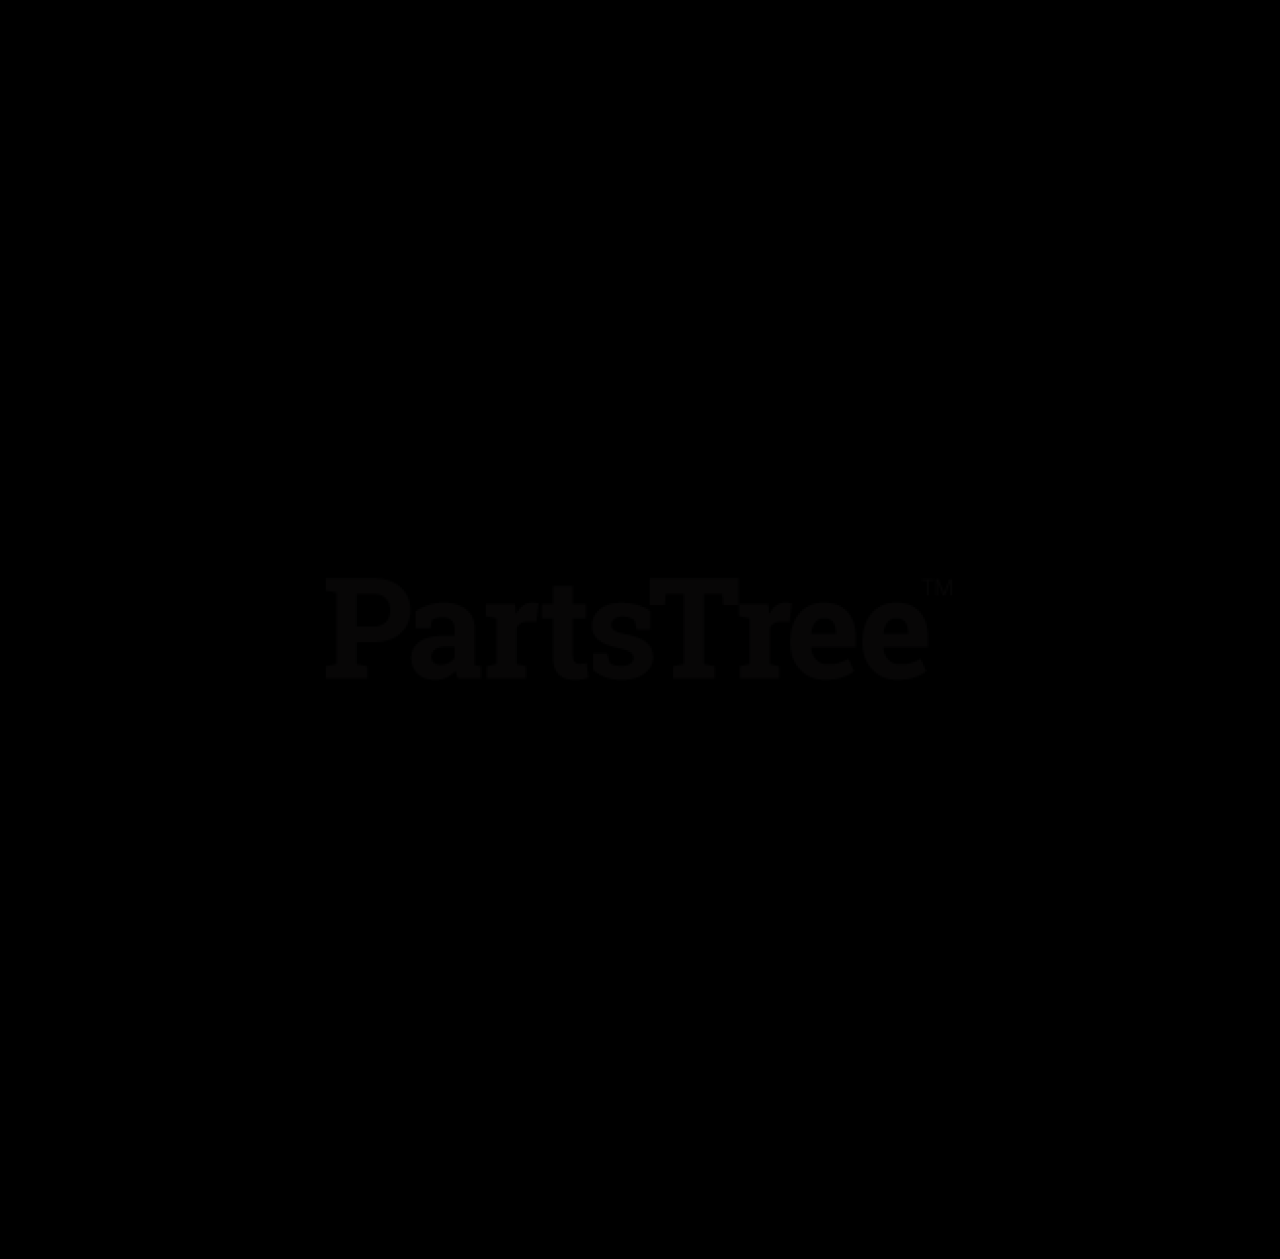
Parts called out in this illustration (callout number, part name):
1	Switch, Ignition
2	Harness, Wiring
3	Weldment, Battery Support
4	Screw, Tapping .38-16 x .75 Hex Washer Head
5	Key, with Cap
6	Hour Meter with Maintenance
7	Switch, Clutch with Retainer Ring
8	Light, Indicator
10	Nut, Locking Top Flange .31-18
11	Gauge, Temperature
12	Bracket, Battery Hold-Down
13	Bolt, Hex .25-20 x .75 Grade 5
14	Mount, Safety Switch
15	Cable, Positive Battery with Boots
16	Cable, Negative Battery
17	Cable Tie
18	Screw, Machine 10-24 x .75 Hex Washer Head
19	Nut, Locking Nylon 10-24 with Insert
20	Boot Terminal, Red (Included with Cable)
21	Switch, Snap Mounting (N.O.) (Included with Seat)
22	Switch, Single Pole (Brake)
23	Screw, Tapping .25-20 x .50 Hex Washer Head
24	Washer, Flat Steel .406 x 1.00 x ..083
25	Diode, Connector Shell
26	Relay (Included with Harness)
27	Fuse, ATO 30 Amp (Included with Harness)
28	Pre-Heat Timer (Included with Engine)
29	Fuse, ATO 60 Amp (Included with Harness)
30	Battery Terminal Boot, Red (Included with Cable)
